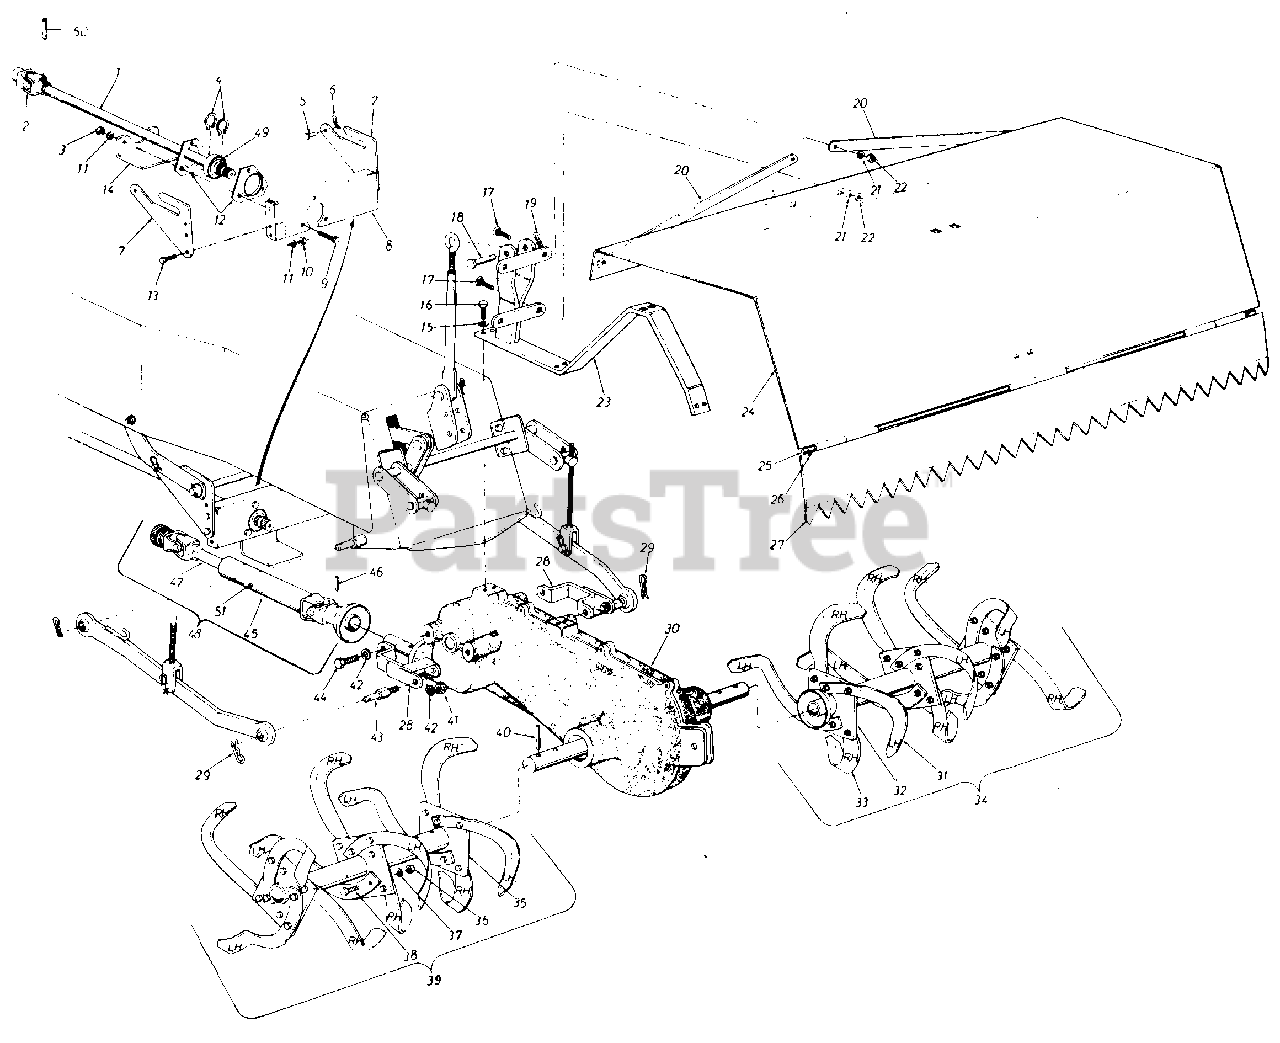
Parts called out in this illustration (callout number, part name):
1	Universal Drive Shaft Ass'y.
2	Universal Joint
3	Hex Nut 5/16-24 Thd.
4	Retaining Ring 1.00" Dia. Shaft
5	Clevis Pin
6	Internal Cotter Pin
7	Hanger Bracket
8	Drive Shaft Brg. Support Brk't
9	Carriage Bolt 5/16-18 x 1.00" Lg.*
10	Hex Nut 5/16-18 Thd.*
11	L. Wash. 5/16" Scr.*
12	Flangette-1" Dia. Shaft
13	Hex Scr. 5/16-24 x .75" Lg.*
14	Bearing Brk't. Guard
15	L.-Wash. 1/2" Scr.*
16	Hex Scr. 1/2-13 x 1.25" Lg.*
17	Carriage Bolt 5/16-18 x 1.00 Lg.*
18	Clevis Pin 5/8" Dia. x 2.4" Lg.
19	Internal Cotter Pin 5/8" Dia.
20	Tiller Cover Strap
21	L.-Wash. 5/16" Scr.*
22	Hex Nut 5/16-18 Thd.*
23	Cover Brk't. Ass'y.
24	Tiller Cover Ass'y .
25	Cover Flap Rod
26	Cotter Pin 1/8" Dia. x 1.00 Lg.*
27	Cover Flap Ass'y.
28	Tiller Pivot Brk't. Ass'y.
29	Internal Cotter Pin 5/8" Dia.
30	Gear Box Ass'y.-Comp.
31	14" Tine-L.H.
32	Mounting Adapter-R.H.
33	14" Tine-R.H.
34	Right Hand Tine Ass'y.-Comp.
35	Mounting Adapter L.H.
36	Hex Nut 3/8-24 Thd.*
37	L.-Wash. 3/8" Scr.*
38	Hex Scr. 3/8-24 x 1.25" Lg.*
39	Left Hand Tine Ass'y.-Comp.
40	Spring Pin Spirol 3/8" Dia. x 2.00" Lg.
41	Hex Cent. L-Nut 5/8-18 Thd.
42	L.-Wash. 5/8" Scr.*
43	Link Clevis Pin
44	Hex Scr. 5/8-11 x 1.50" Lg.*
45	Universal Drive Shaft-Female Ass'y.
46	Spring Pin Spirol 5/16" Dia. x 1.75" Lg.
47	Universal Drive Shaft-Male Ass'y.
48	Universal Drive Shaft Ass'y.
49	Ball Bearing 1.0" I.D.
50	Spring Pin Spiral 5/16" x 2.50" Lg.
51	Spring Pin Spiral 1/4" Dia. x 1.00" Lg.
